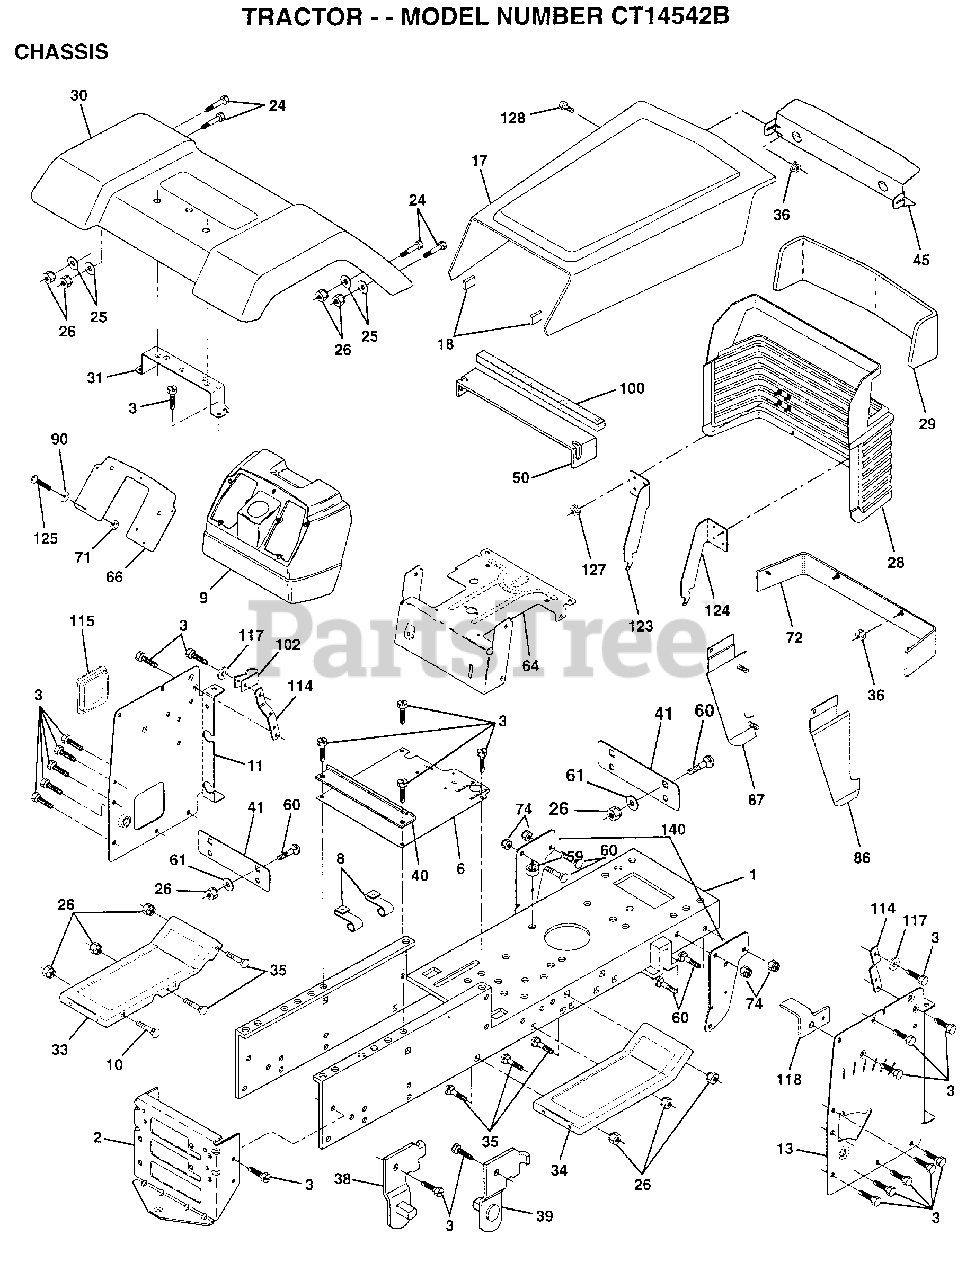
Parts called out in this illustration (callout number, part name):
1	CHASSIS WLDMT 11G
3	SCREW
8	"CLIP,INSULATOR"
9	DASH.PLASTIC.BLK
11	PANEL.DASH.LH.
13	PANEL.DASH.RH.
17	HOOD/GRILLE ASM
24	BOLT
25	WASHER
26	NUT
28	GRILLE ASM WELD
31	BRACKET SUPT FEND
33	FOOTREST.LH.PERF.
34	FOOTREST.RH.PERF.
35	BOLT
36	PAL NUT LT
38	BRACKET ASM LH
39	BRACKET ASM RH
40	SPACER FENDER LT
41	PLATE EXTEN FEND
50	"BAFFLE,HOOD"
60	BOLT
61	WASHER
64	DASH.LOWER.LT
66	PLATE DASH SILKSC
71	NUT HXKEP 1/4X20
72	STRAP FENDER ASM
86	PANEL SIDE RH ASM
87	PANEL SIDE LH ASM
90	WASHER PM
100	FOAM STRIP T
102	CLIP T
114	BRACKET.SUPT.DASH
115	COVER ACCESS
117	WASHER.SERRATED.
118	BRACKET.CLUTCH.MC
123	BRACKET.PICK.LH.
124	BRACKET.PICK.RH.
125	SCREW
127	PAL NUT
128	SCREW SPECIAL
